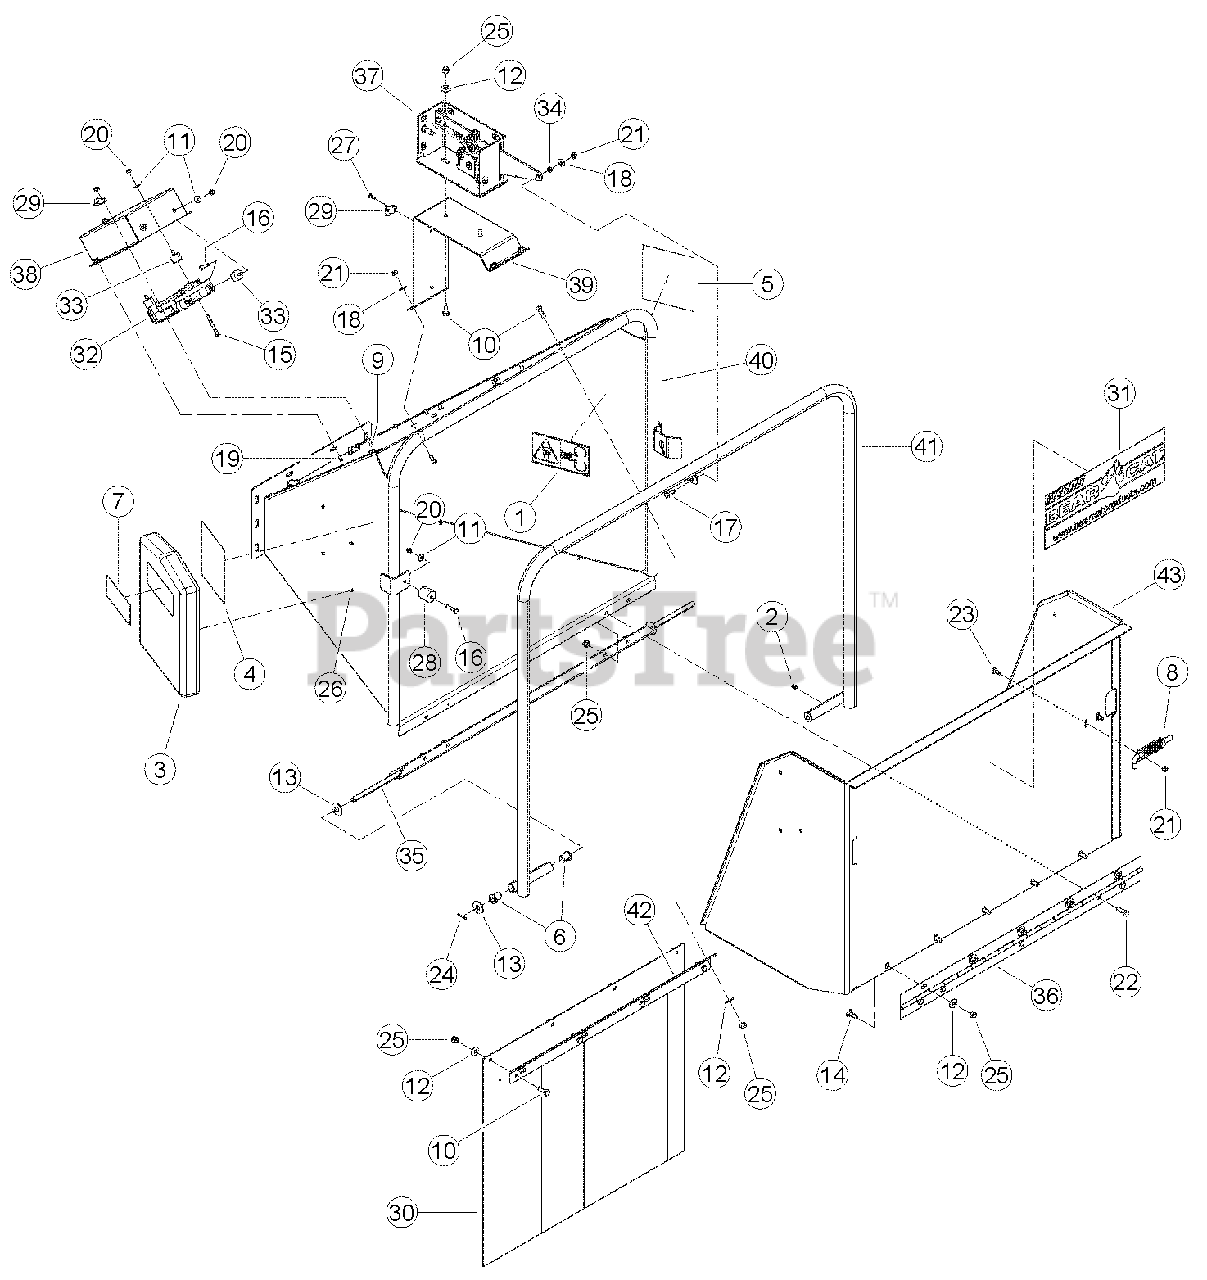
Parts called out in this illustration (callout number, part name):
1	DECAL, BLADE DANGER ISO
2	FITTING, 1/4 SELF-TAP GREASE
3	CONTAINER, INSTRUCTION MANUAL
4	DECAL, FEED POSITION
5	DECAL, FEED POSITION
6	BUSHING, 1/2 X 1 FLANGE LUBE
7	DECAL, MULTILINGUAL MANUAL
8	LATCH, RH HINGE
9	BOLT, 1/4 X 1 HEX HD GR5 ZP
10	BOLT, 3/8 X 1 HEX HD GR5 ZP
11	WASHER, 1/4 FLAT ZP
12	WASHER, 3/8 FLAT ZP
13	WASHER, 1/2 FLAT ZP
14	BOLT, 3/8 X 1 CRG GR5 ZP
15	BOLT, 1/4 X 2-1/4 HEX HD GR5 ZP
16	BOLT, 1/4 X 1-1/4 HEX HD GR5 ZP
17	BOLT, 5/16 X 1 HEX HD GR5 NC ZP
18	WASHER, 5/16 FLAT ZP
19	BOLT, 1/4 X 5/8 HEX HD GR5 ZP
20	NUT, 1/4 NE NYLOCK ZP
21	NUT, 5/16 NE NYLOCK ZP
22	BOLT, 3/8 X 1-1/4 HEX HD GR5 ZP
23	BOLT, 5/16 X 3/4 CRG GR5 NC ZP
24	PIN, 1/8 X 1 COTTER ZP
25	NUT, 3/8 NE NYLOCK ZP
26	RIVET, AL BLIND 1/4 X 1/2 DOME HEAD
27	RIVET, AL BLIND 1/4 X 3/4 DOME HEAD
28	BUMPER, RECESSED RUBBER
29	CLAMP, CABLE MOUNT
30	FLAP, CHUTE
31	DECAL, BEARCAT WEB
32	CONTROLLER, PLUS 1 CHIPPER
33	BUMPER, 1 OD. W/1/4 STUD
34	SPACER, IDLER PIVOT
35	WELDMENT, CONTROL PIVOT
36	HINGE, EXTENSION TRAY
37	ASSEMBLY, SWITCH BOX
38	ENCLOSURE, PLUS 1 MOUNT
39	MOUNT, SWITCH BOX
40	WELDMENT, CHIPPER CHUTE
41	WELDMENT, CONTROL ARM
42	SUPPORT, CHIPPER FLAP
43	WELDMENT, EXTENSION TRAY W/O TABS
